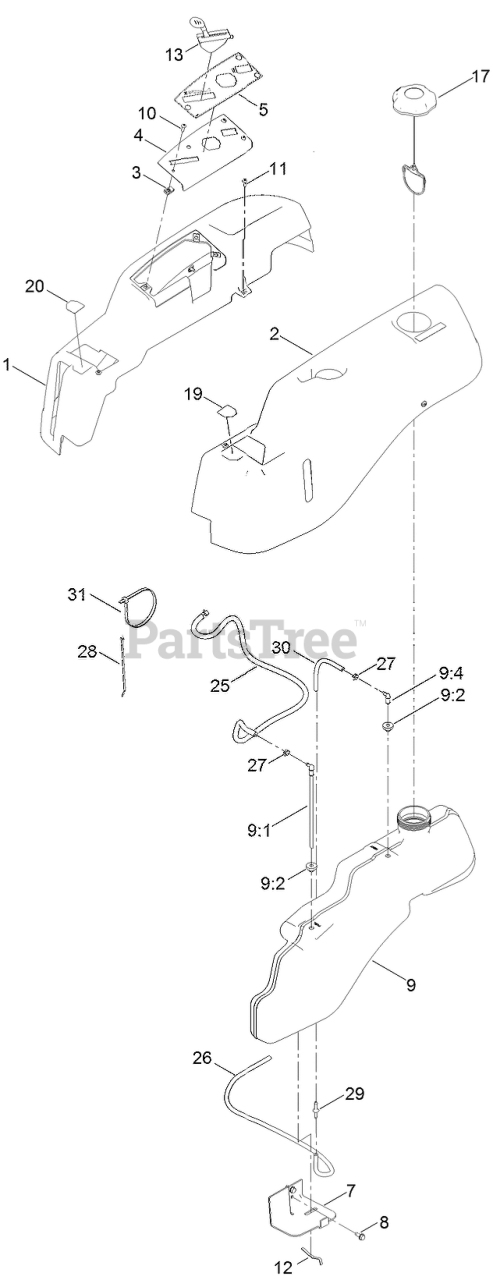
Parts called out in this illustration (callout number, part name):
1	POD-RH
2	POD-LH
4	PLATE-CONTROL
5	DECAL-PANEL, CONTROL
7	SUPPORT-TANK, FRONT
8	SCREW-HWHTF
9	FUEL TANK ASM
9:1	CONNECTOR-ELBOW, 90 DEG
9:2	BUSHING
9:4	FITTING-PLASTIC
10	SCREW-PRH
11	SCREW-SHOULDER
12	SPRING
13	CABLE-THROTTLE AND CHOKE
17	CAP-FUEL, RATCHETING
19	DECAL-LEVER, CONTROL (LH)
20	DECAL-LEVER, CONTROL (RH)
25	HOSE-FUEL
26	HOSE-FUEL
27	CLAMP-HOSE
28	TIE-CABLE
29	ADAPTOR-ORIFICE
30	HOSE-FUEL
31	TIE-CABLE
